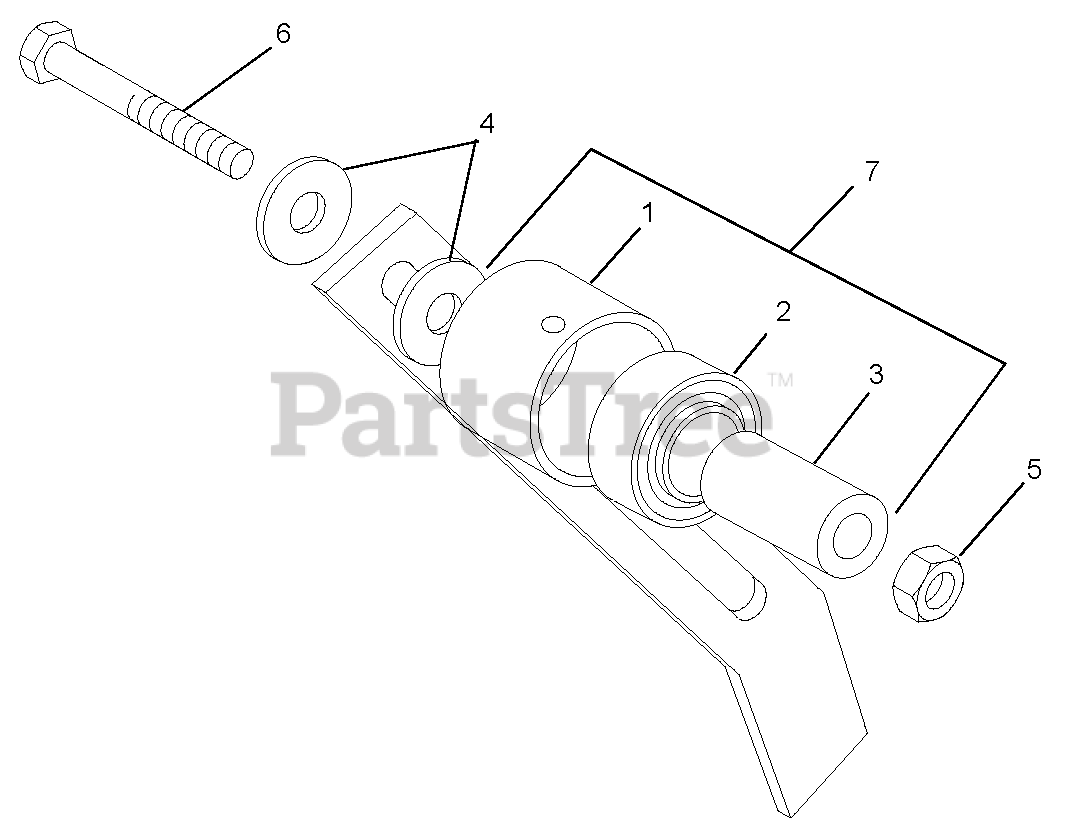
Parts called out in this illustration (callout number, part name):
1	Shell Idler 2.50"
2	Bearing 1.000 ID x 2.0472 OD
3	Bushing, Idler
4	Washer, Flat .50 SAE
5	Nut, Hex .50-13 Nylock
6	Cap Screw, Hex Head .50-13 x 3.50
7	Idler Assembly 2.50"
